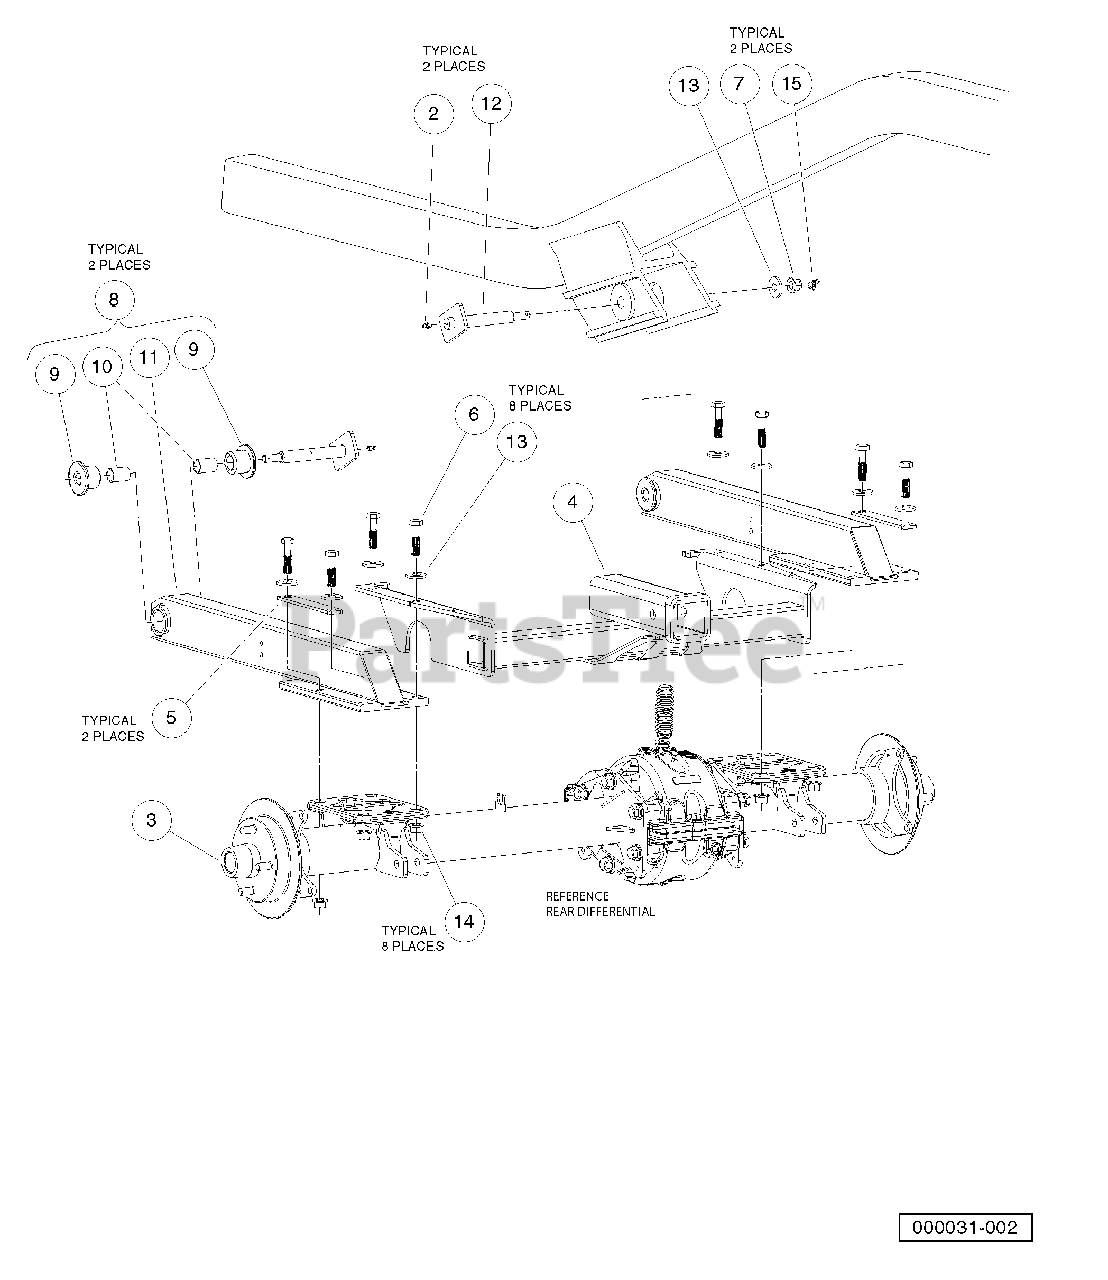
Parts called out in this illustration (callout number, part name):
1	Instl, Rear Suspension
2	Fitting, 1/4-28 Thread-Forming Grease
3	Center Cap, Rubber
4	Weldment, Receiver, Rear
5	Washer, Strip, Swingarm
6	Bolt Flanged Head, M12 X 1.75 X 50
7	Nut Flg, M12x1.75, Nylon Gr 10
8	Sub Asm Swingarm
9	Bushing, Pivot, Urethane
10	Bushing, Teflon
11	Swingarm, Rear, Awd
12	Pin, Swingarm, Weldment
13	Washer, M12 Hard Regular
14	Nut Flg M12 X 1.75 Cl10
15	Cotter, Rue Ring, 1/2"
